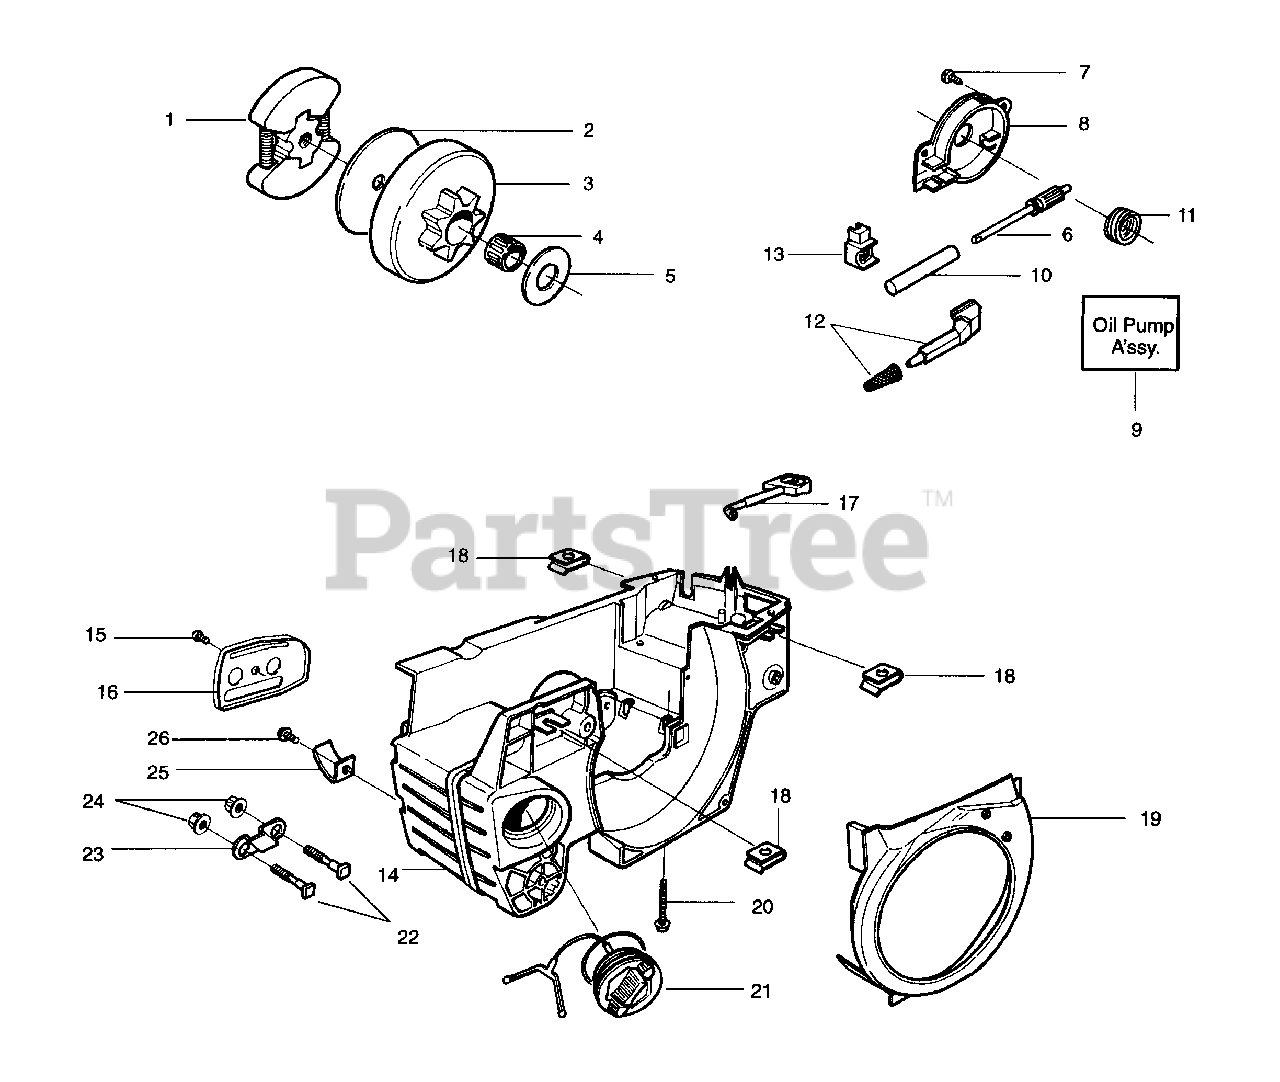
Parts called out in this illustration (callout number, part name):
1	Clutch Assembly
2	Clutch Washer
3	Clutch Drum
4	Clutch Bearing
5	Thrust Washer
6	Plunger & Gear Assembly
8	Oil Pump Housing
9	Oil Pump Assembly
10	Oil Pump Barrel
11	Oil Pump Worm
12	Oil Pick-Up and Screen Assembly
13	Oil Seal
14	Chassis & Tank Assy.
17	Choke Lever
18	Type "U" Speed Nut
19	Baffle Plate
23	Bar Stud Plate
25	Chain Catcher
